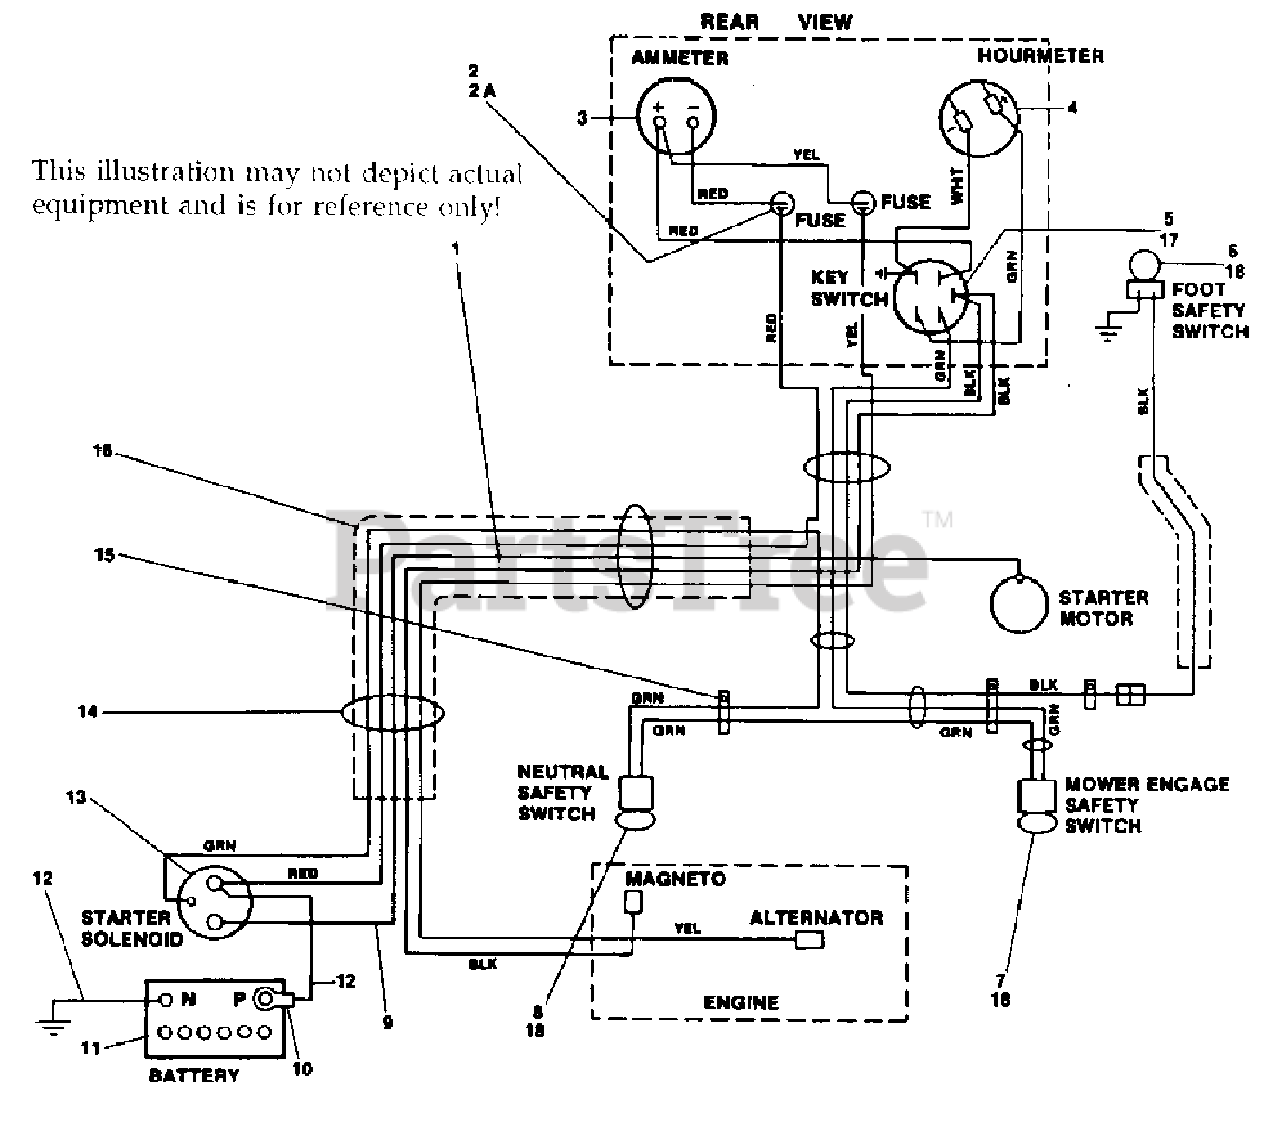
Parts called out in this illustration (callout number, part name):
1	WIRING HARNESS, COMPLETE(18KH)
2	FUSE HOLDER
2A	FUSE, 20A
3	AMMETER
4	HOUR METER
5	KEY SWITCH
6	FOOT SAFETY SWITCH
7	MOWER ENGAGE SAFETY SWITCH
8	NEUTRAL SAFETY SWITCH
9	BATTERY CABLE
10	RUBBER BOOT
11	BATTERY
12	BATTERY CABLE
13	STARTER SOLENOID
14	CABLE TIE
15	CABLE CLAMP
16	PLASTIC CONDUIT
17	CONNECTOR, STARTER SWITCH
18	CONNECTOR, SAFETY SWITCH
